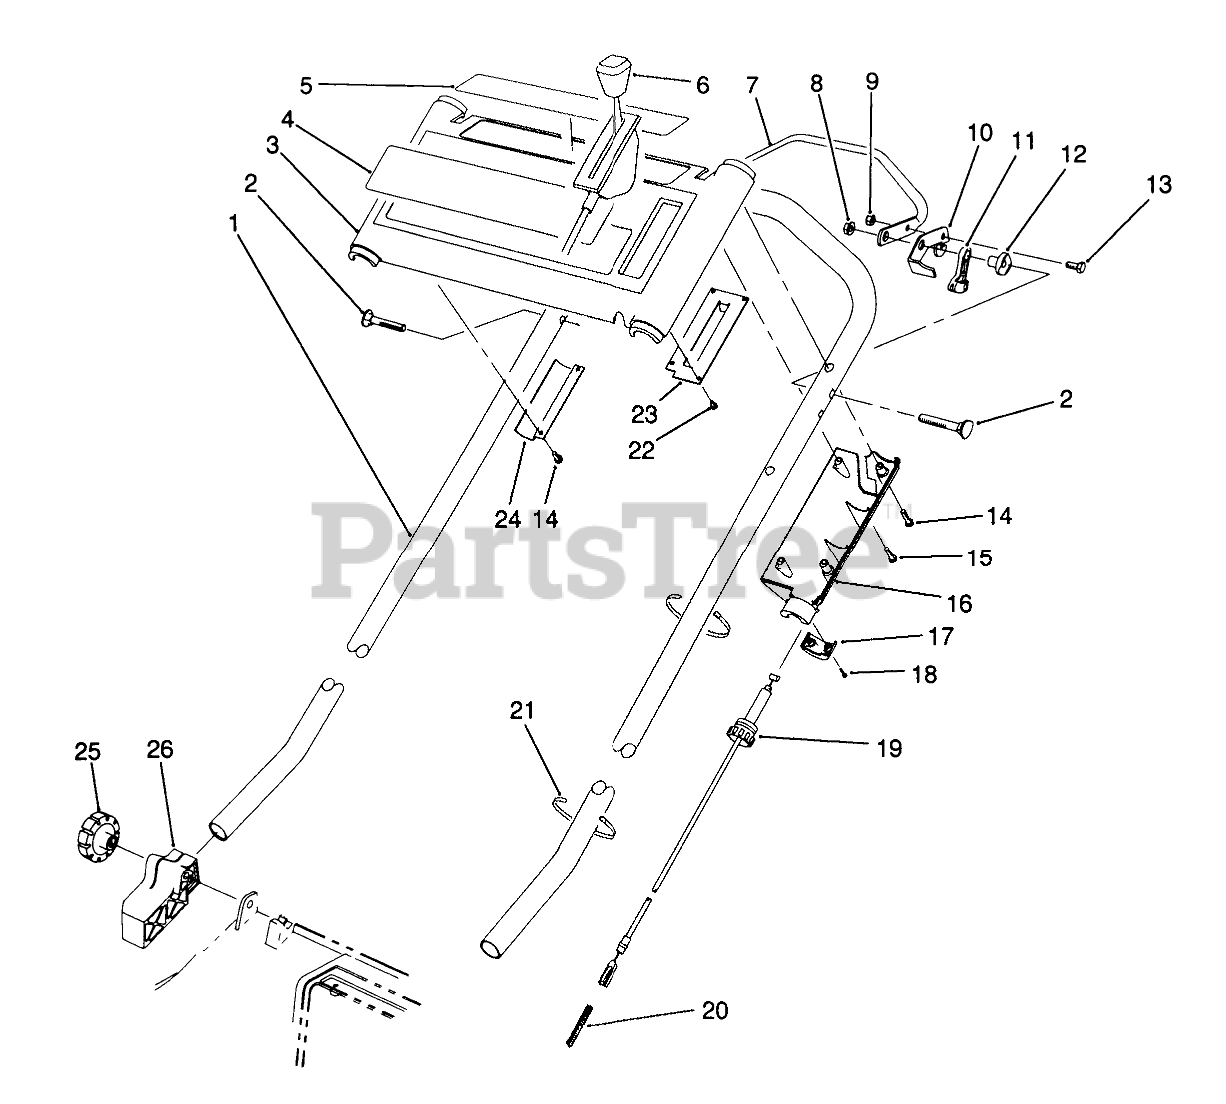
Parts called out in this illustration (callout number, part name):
1	Handle
2	SCREW-HANDLE
3	Panel-Control (Incl. Ref #4, & 5)
4	DECAL - TORO
5	DECAL - PANEL DANGER
6	THROTTLE CONTROL
7	CONTROL BAR
8	NUT-LOCK, NI
9	NUT-LOCK, NI
10	CONTROL LEVER
11	LEVER-TRACTION
12	SPACER-SUPPORT
13	SCREW-HH
14	SCREW-PPH, PLASTITE
15	Screw
16	Cover-Throttle Lower
17	LOWER THROTTLE CAP
18	#4-14X.62 PLASTITE SCW
19	TRACTION CABLE
20	SPRING-COMPRESSION
21	TIE-CABLE
22	#6-19X.25 PLASK FORM SC
23	THROTTLE PLATE
24	Bracket-Panel
26	MOUNT-HANDLE, RH
